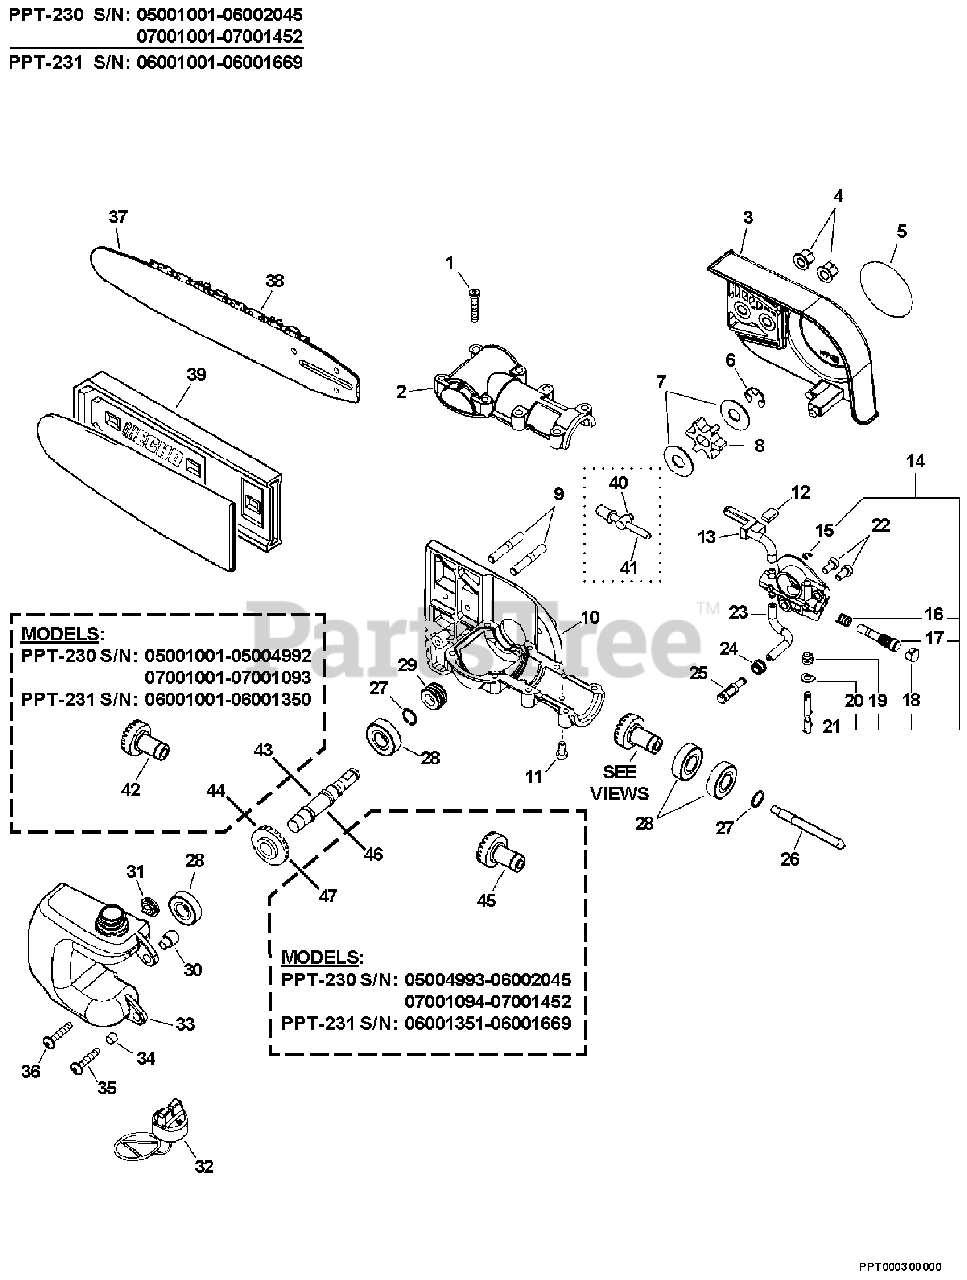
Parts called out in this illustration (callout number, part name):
1	SCREW - 5X25
2	CASE, GEAR - UPPER
3	GUARD, SPROCKET
4	NUT - 6 -- FLANGE
5	LABEL - ECHO
6	RING, RETAINING
8	SPROCKET, DRIVE
9	STUD - 6
10	GEAR CASE ASSY - LOWER
11	SCREW - 5X10
12	PAD, FOAM
13	PIPE, OIL OUTLET
14	AUTO-OILER ASSY
15	RING, RETAINING
16	SPRING, PLUNGER
17	PLUNGER ASSY
18	CAP, OIL PUMP
21	NEEDLE, ADJUST
22	SCREW - 5X10
23	PIPE - 3X6X75 -- BLACK
24	GROMMET
25	FILTER, OIL
26	CONNECTOR, SHAFT
27	RING, RETAINING - 12
28	BEARING, BALL - 6001
29	GEAR - WORM
32	CAP ASSY
33	TANK, OIL
35	SCREW - 5X16
36	SCREW - 5X20
37	GUIDE BAR - 10" (25cm) Intenz
38	SAW CHAIN - 10" (25cm)
39	COVER, GUIDE BAR - 10" (25cm)
40	TENSIONER, CHAIN
41	SCREW, TENSIONER
42	GEAR - BEVEL
43	GEAR - SHAFT
44	GEAR - BEVEL
45	GEAR - BEVEL
46	GEAR - SHAFT
47	GEAR - BEVEL
